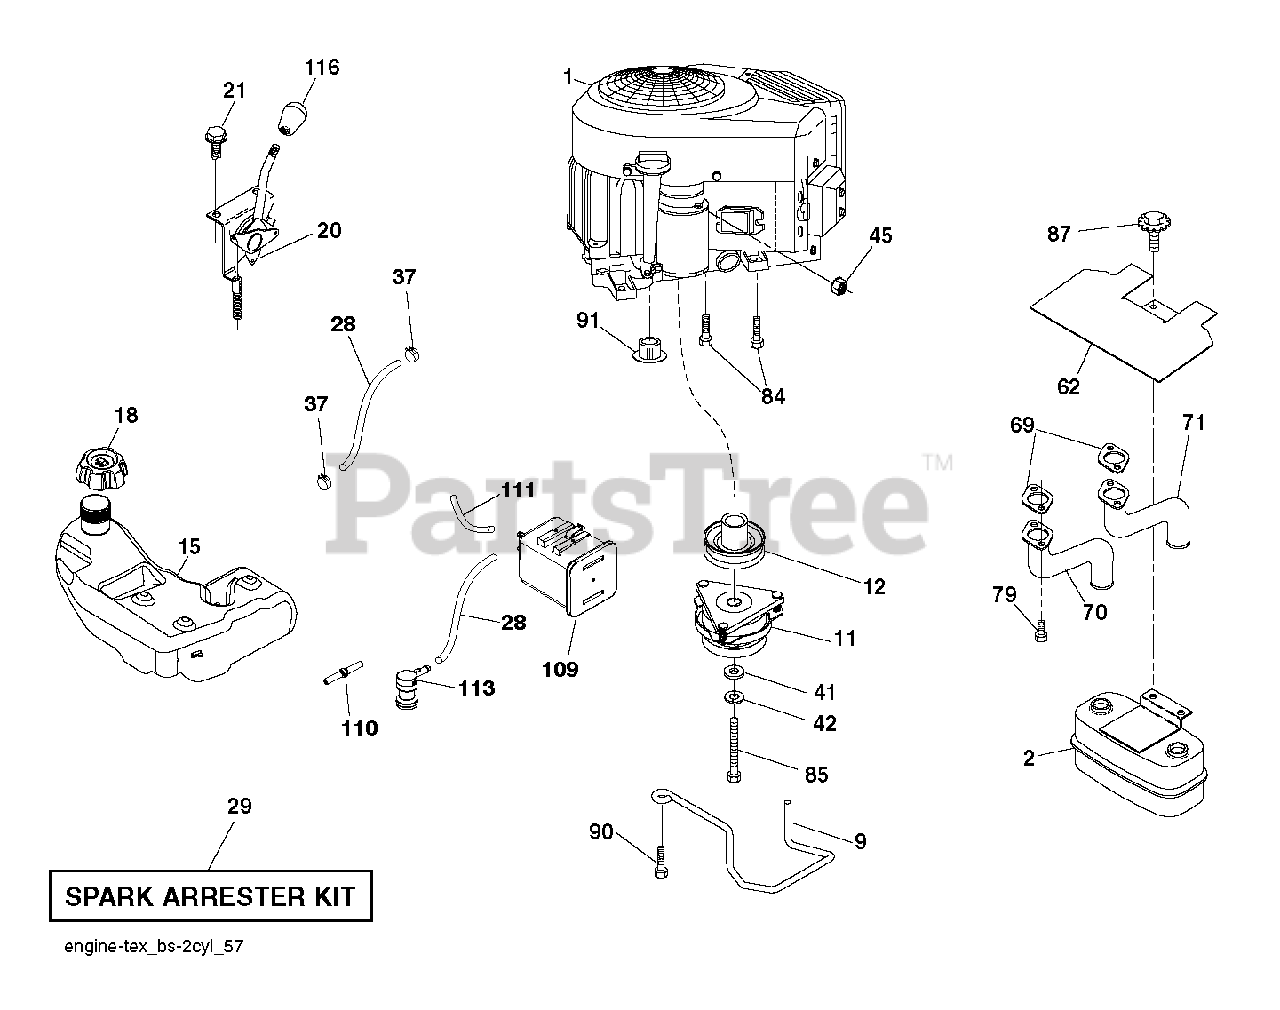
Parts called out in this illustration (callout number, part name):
2	MUFFLER.TWIN.CYL.LOW.TONE
9	KEEPER.BELT.ENGINE.4.2
11	CLUTCH.ELECTRIC.LT.48"*
12	PULLEY.ENGINE.TUFFTORQ
15	TANK.ASM.FUEL.3GA.CARB
18	CAP.ASM.FL.RITCH.3"E10.SYM.498
20	CONTROL THROTTLE/CHOKE
21	SCREW.#10 X 0.750.BOS
28	LINE.FUEL.64"REAR.EMIS
29	KIT.SPARK ARRESTOR 794945 B&S
37	HOSE CLAMP
42	LOCKWASHER
45	NUT
62	SHIELD.HEAT.MUFFLER
69	GASKET.MUFFLER
70	RP.EXHAUST.TUBE.LH.BS/TWIN
71	EXHAUST.TUBE.RH.BS/TWIN
79	SCREW.SOCKET.HEAD.5/16-18
84	SCREW.3/8-16
85	BOLT HEX 7/16-20X4-1/4"
87	Bolt, 5/16-18 X 1-3/4
90	SCREW 3/8-16X1
91	BUSHING.1.375OD
109	CANNISTER, CARBON
110	VALVE.ASM.ANTI-SLOSH
111	RP PURGE LINE
113	VALVE.SLANT.CARTRDG.90 DEG.TEX
116	KNOB - SHIFT
